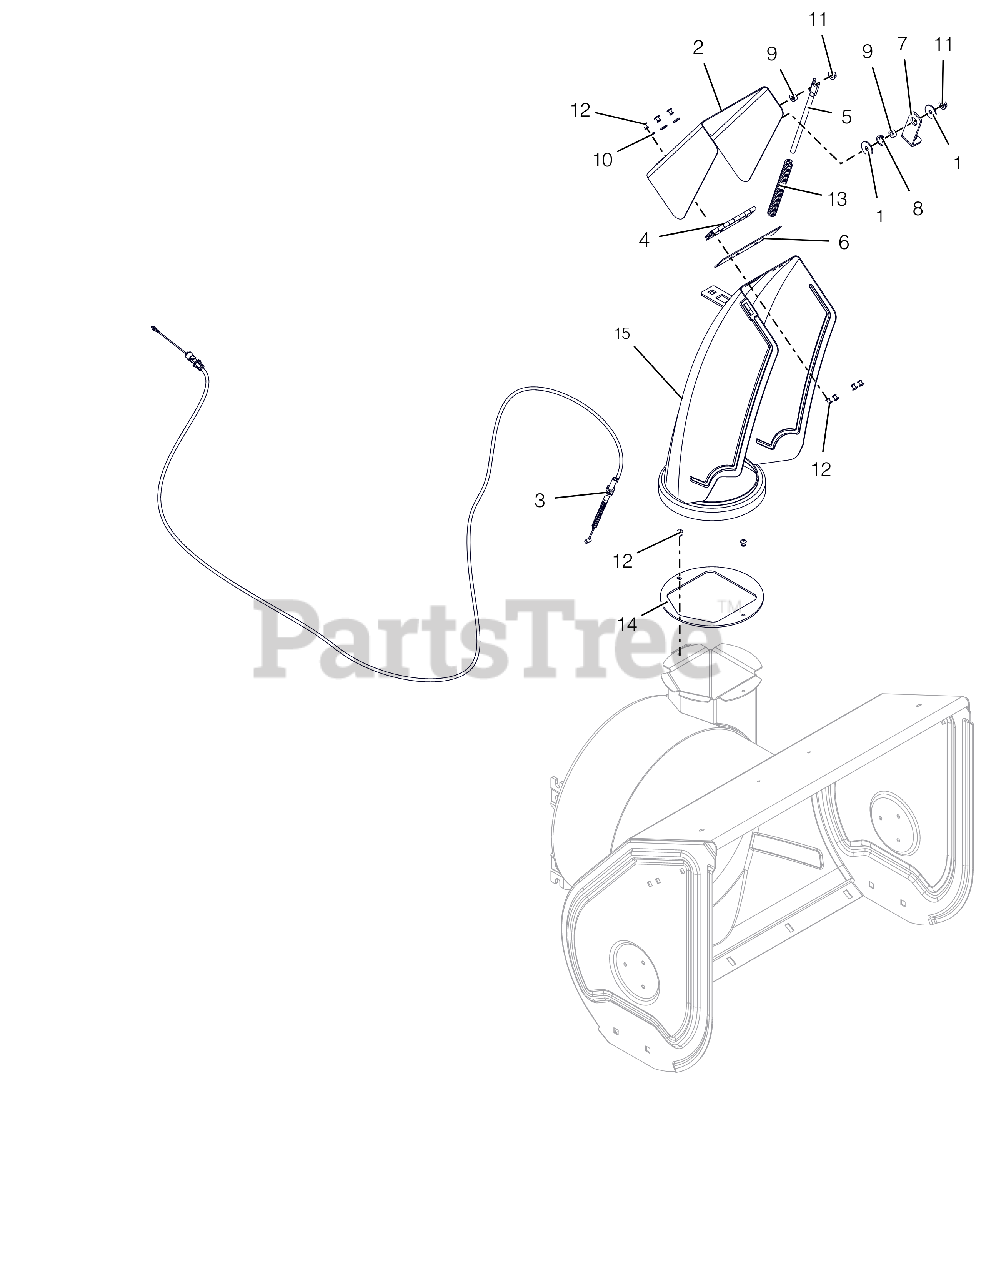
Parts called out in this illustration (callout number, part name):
1	WSHR-FL-STL .281X1.000X.063
2	CAP, LARGE REMOTE (W/DECAL)
3	CABLE, DEFLECTOR - DELUXE
5	ROD, DEFLECTOR CAP
6	CAP SEAL 5.50
7	BRACKET, CABLE ANCHOR
8	BUSHING, POLYLINER-.50 SNAPIN
9	BSHG-SLV .265X.500X.219
10	WSHR-FL-STL .196X.500X.06 YZ
11	@NUT-LK-CTR-FLG .25-20 YWZC
12	RVT-POP .187 YZ
13	SG-COMP .08X.40X6.50 14#/IN
14	BAFFLE, DISCHARGE NECK
15	CHUTE,DISCHARGE,RMT,ID
15	KIT, DISCHARGE CHUTE W/DEF ID
